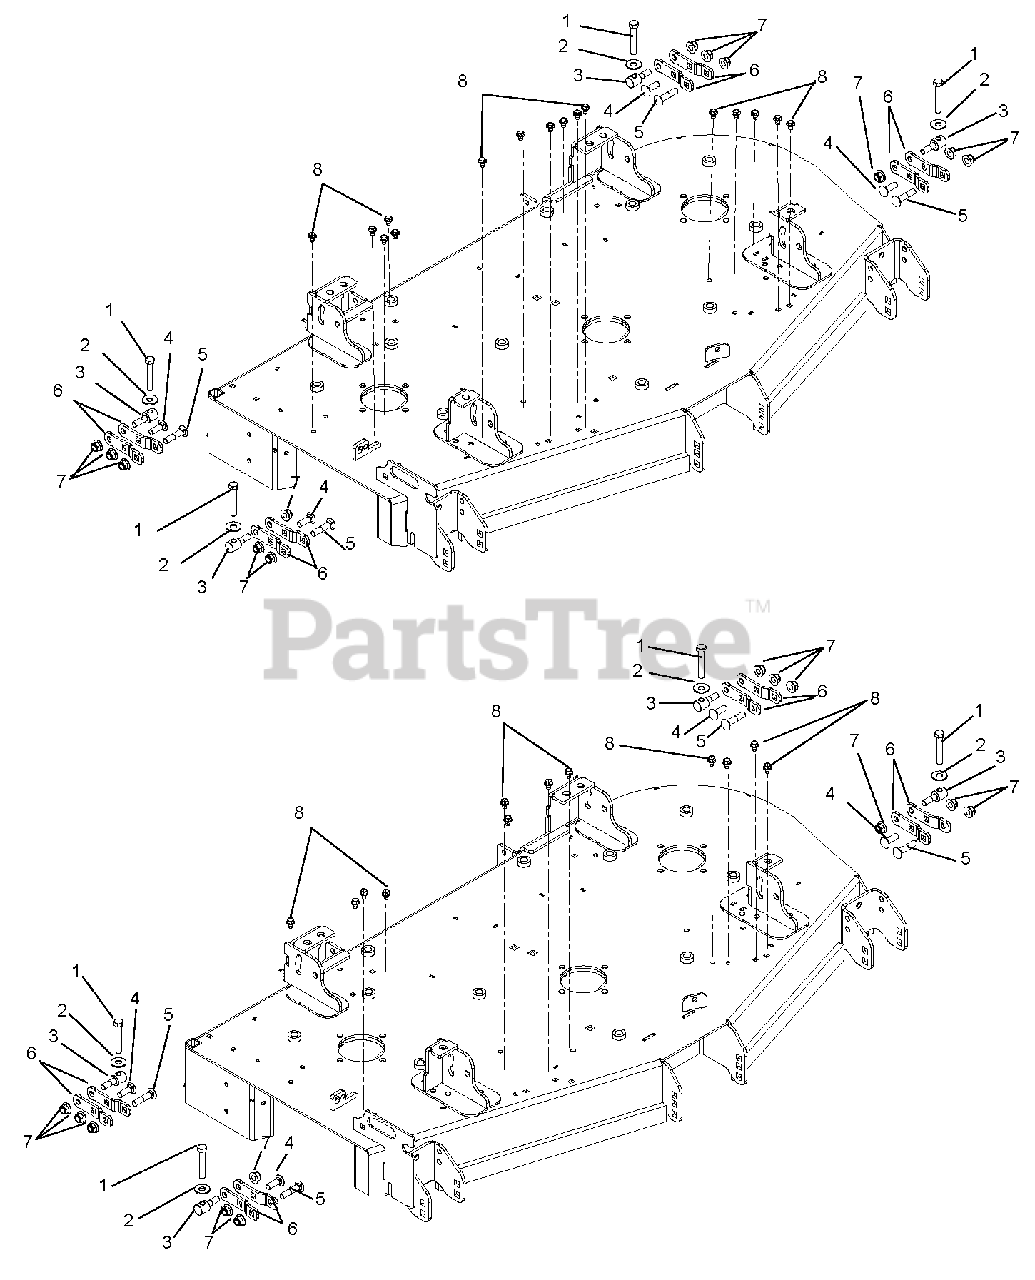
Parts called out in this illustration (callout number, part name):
1	Bolt, Hex .50-13 x 3.00 Grade 5 Full Thread
2	Washer, Flat Steel .563 x 1.38 x .109
3	Trunnion, .50-13
4	Bolt, Round Head Square Neck .50-13 x 1.50 Grade 5
5	Bolt, Round Head Square Neck .50-13 x 2.25 Grade 5
6	Deck Leveling Bracket – Black
7	Nut, Locking Nylon Flange .50-13
8	Screw, Tapping .38-16 x .50 Hex Washer Head
